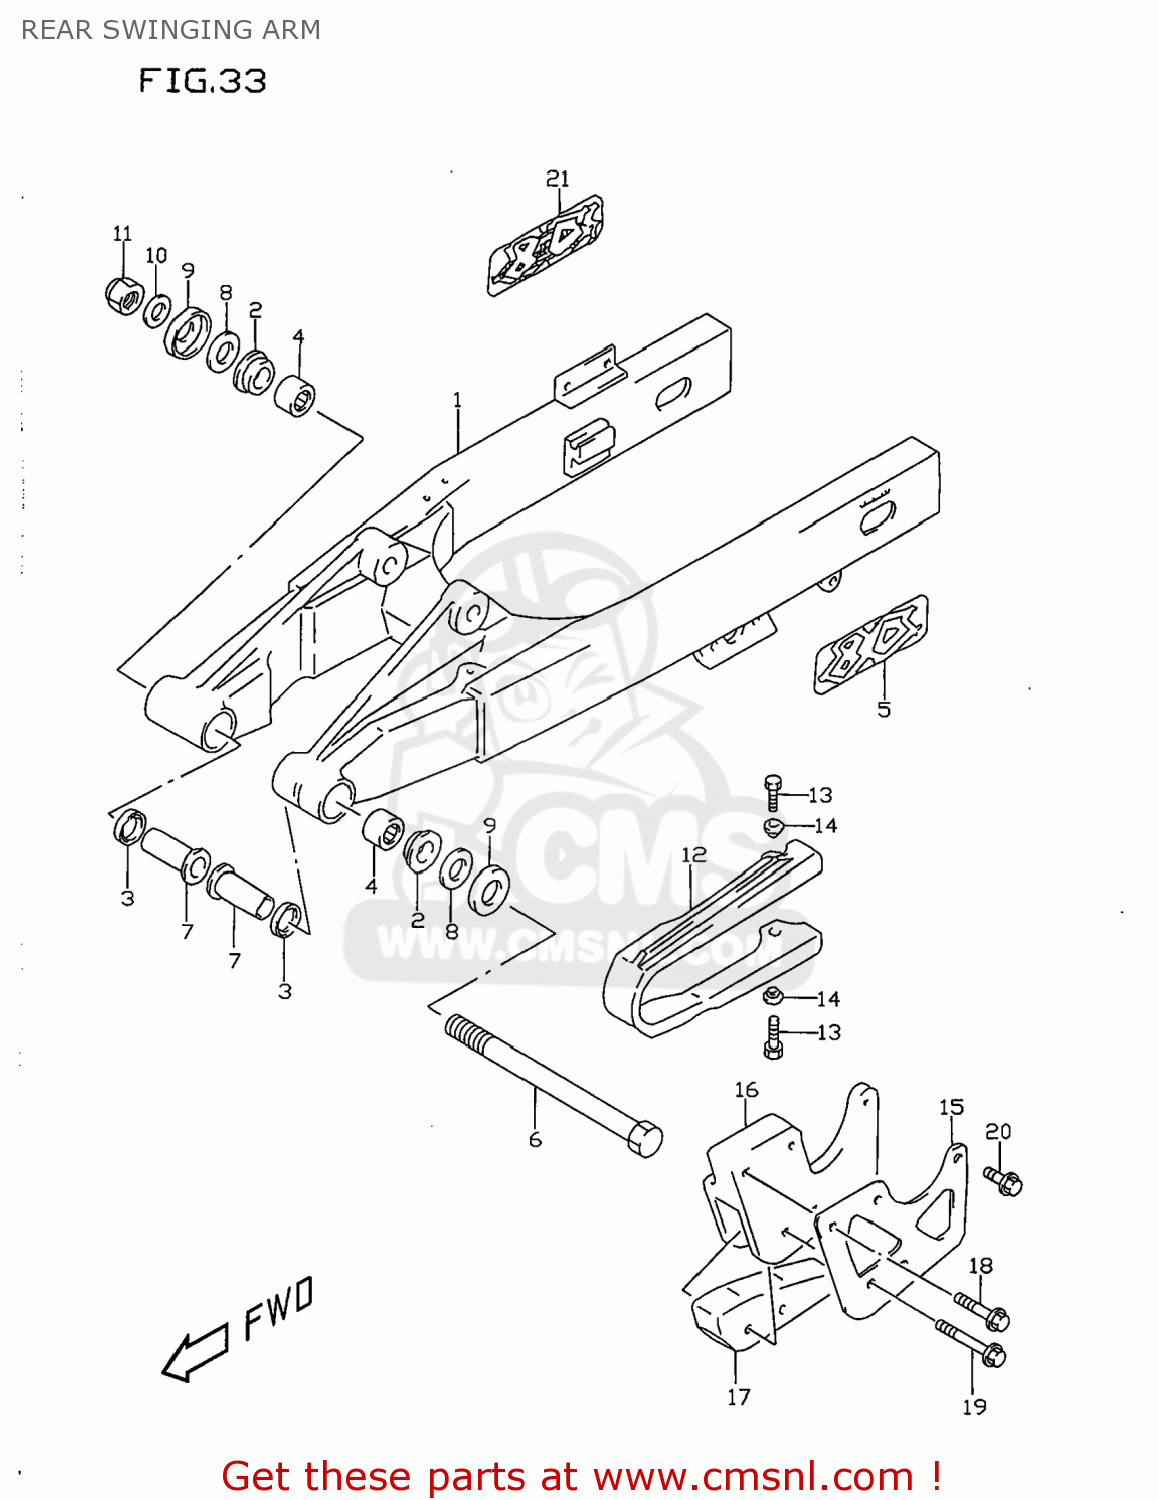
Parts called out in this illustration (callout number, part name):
1	SWINGINGARM ASSY,RR
2	BUSHING,SWGARM PIVOT
3	SEAL,OIL(17X24X3)
4	BEARING(17X24X30)
5	EMBLEM,SWING ARM
6	SHAFT,RR SWINGINGARM PIVOT
7	SPACER,RR SWGARM PIVOT
8	WASHER
9	COVER,SWGARM PIVOT
10	WASHER
11	NUT 12MM
12	BUFFER,CHAIN TOUCH DEFENSE
13	BOLT
14	WASHER
15	PLATE,GUIDE CHAIN OUTER
16	GUIDE,CHAIN
17	DEFENSE,CHAIN GUIDE
18	BOLT,G/S SWITC
19	BOLT
20	BOLT
21	EMBLEM,SWINGINGARM
